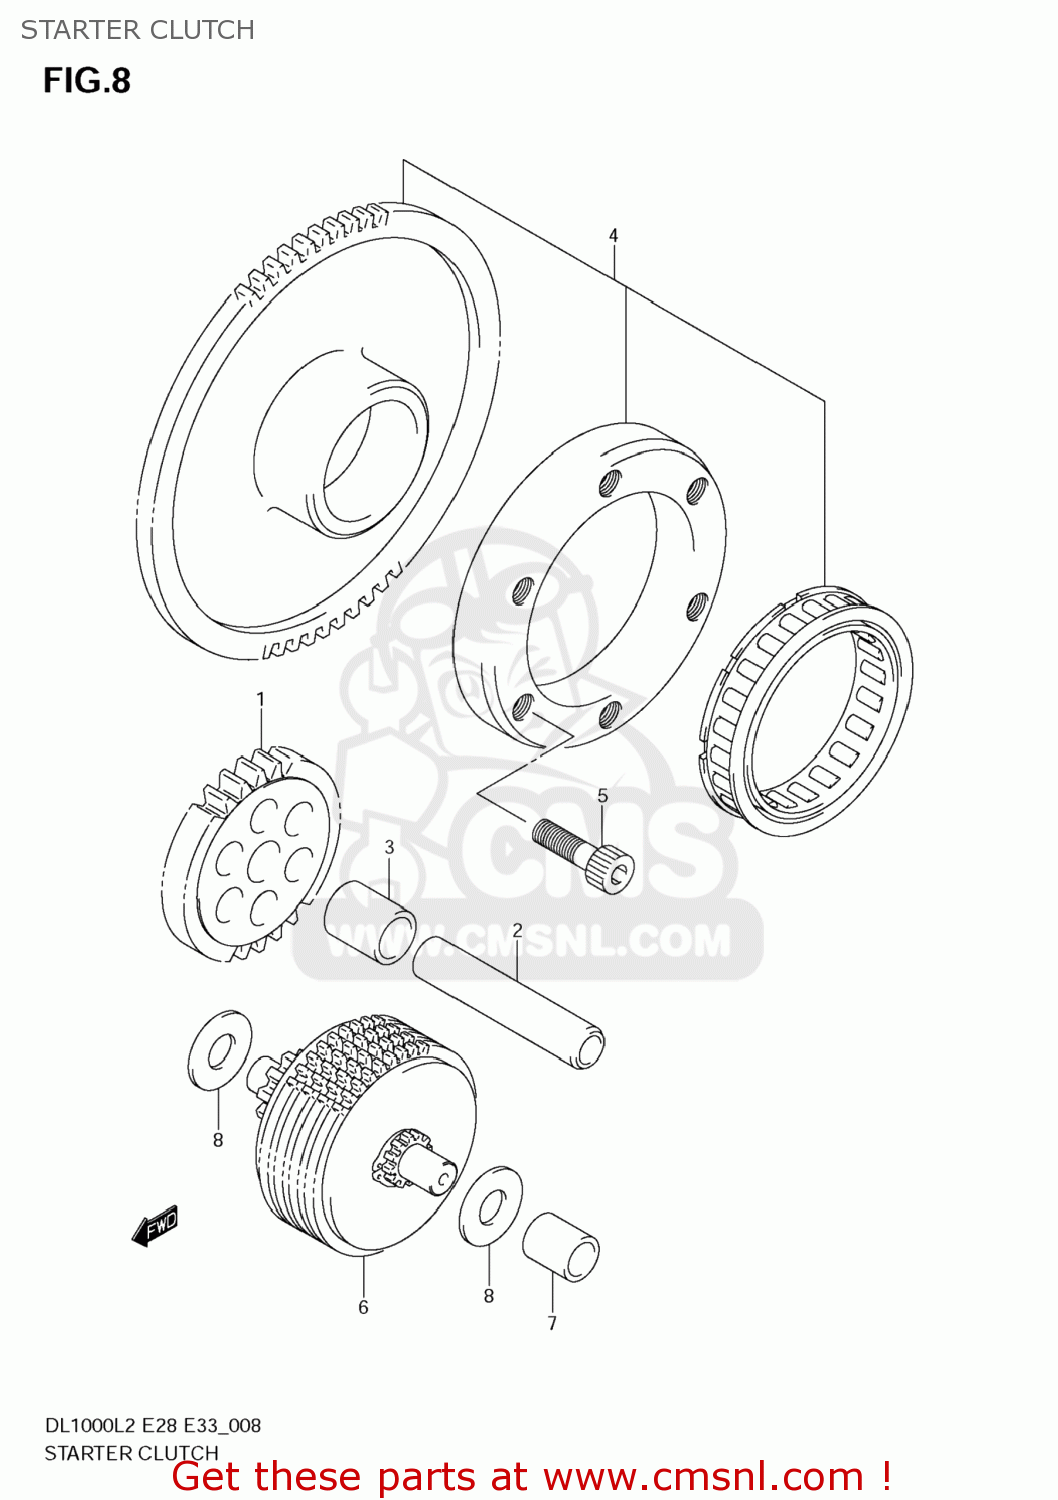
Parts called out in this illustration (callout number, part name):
1	GEAR,STARTER IDLE NO.2
2	PIN(7X12X50.5)
3	SPACER(12.5X19X17.5)
4	CLUTCH SET,STARTER
5	BOLT(8X20)
6	LIMITER ASSY,START ID GR NO.1
7	BUSH,LIMITER GEAR SHAFT
8	WASHER
